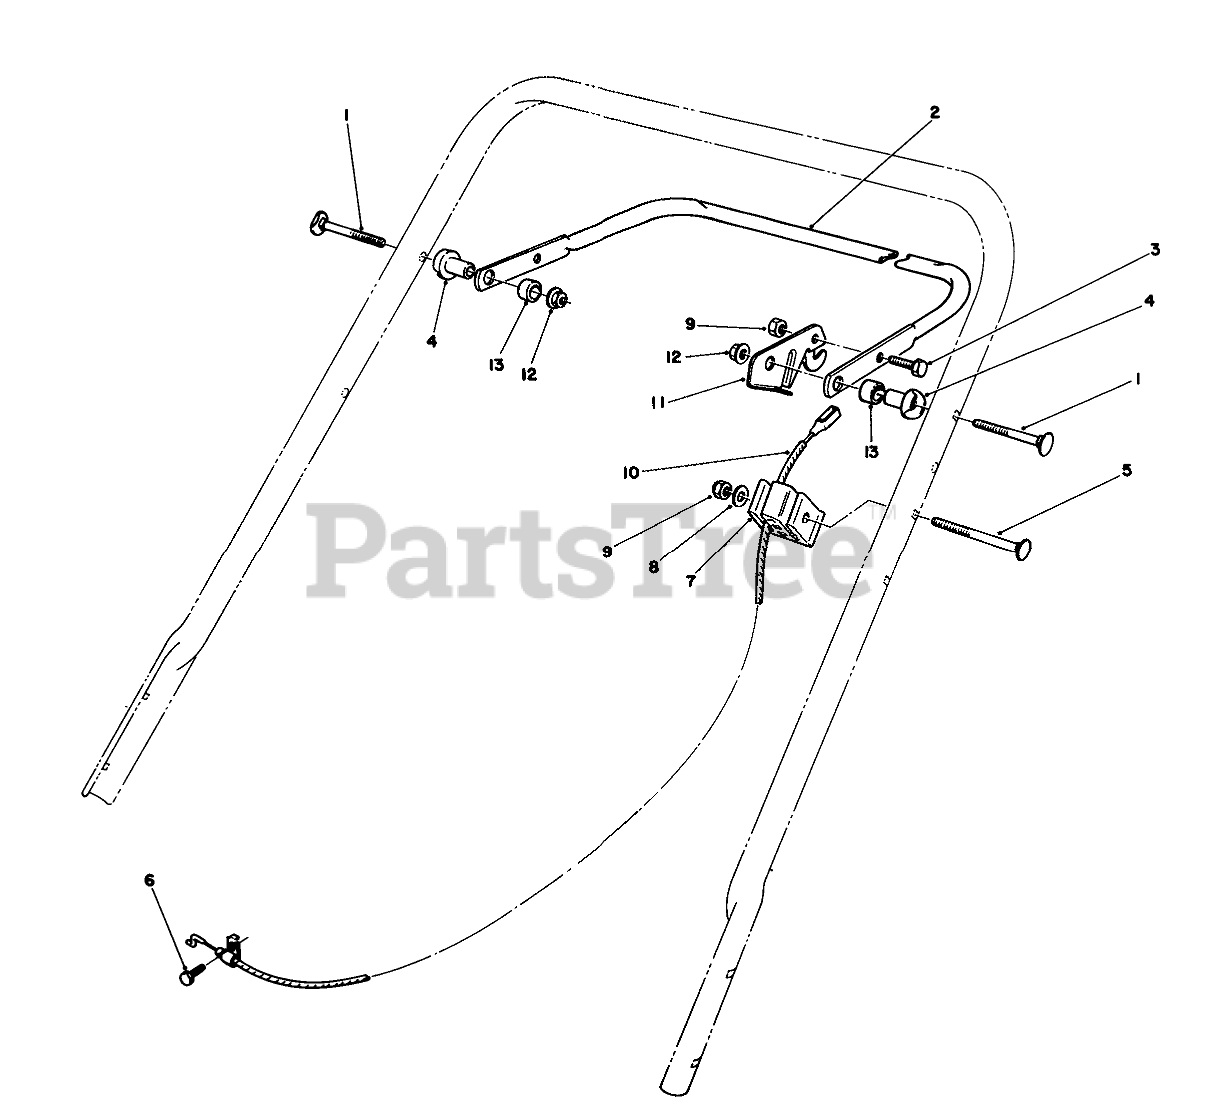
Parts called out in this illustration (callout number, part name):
1	5/16-18 X 2 HNDLE SCREW
2	Bar-Control
3	SCREW-HH
4	SPACER-SUPPORT
5	HANDLE SCREW
6	SCREW-HH
7	SUPPORT-CABLE
8	WASHER-FLAT
9	NUT-LOCK, NI
10	BRAKE CABLE
11	LEVER-CONTROL
12	NUT-LOCK, NI
13	SPACER-NYLON
